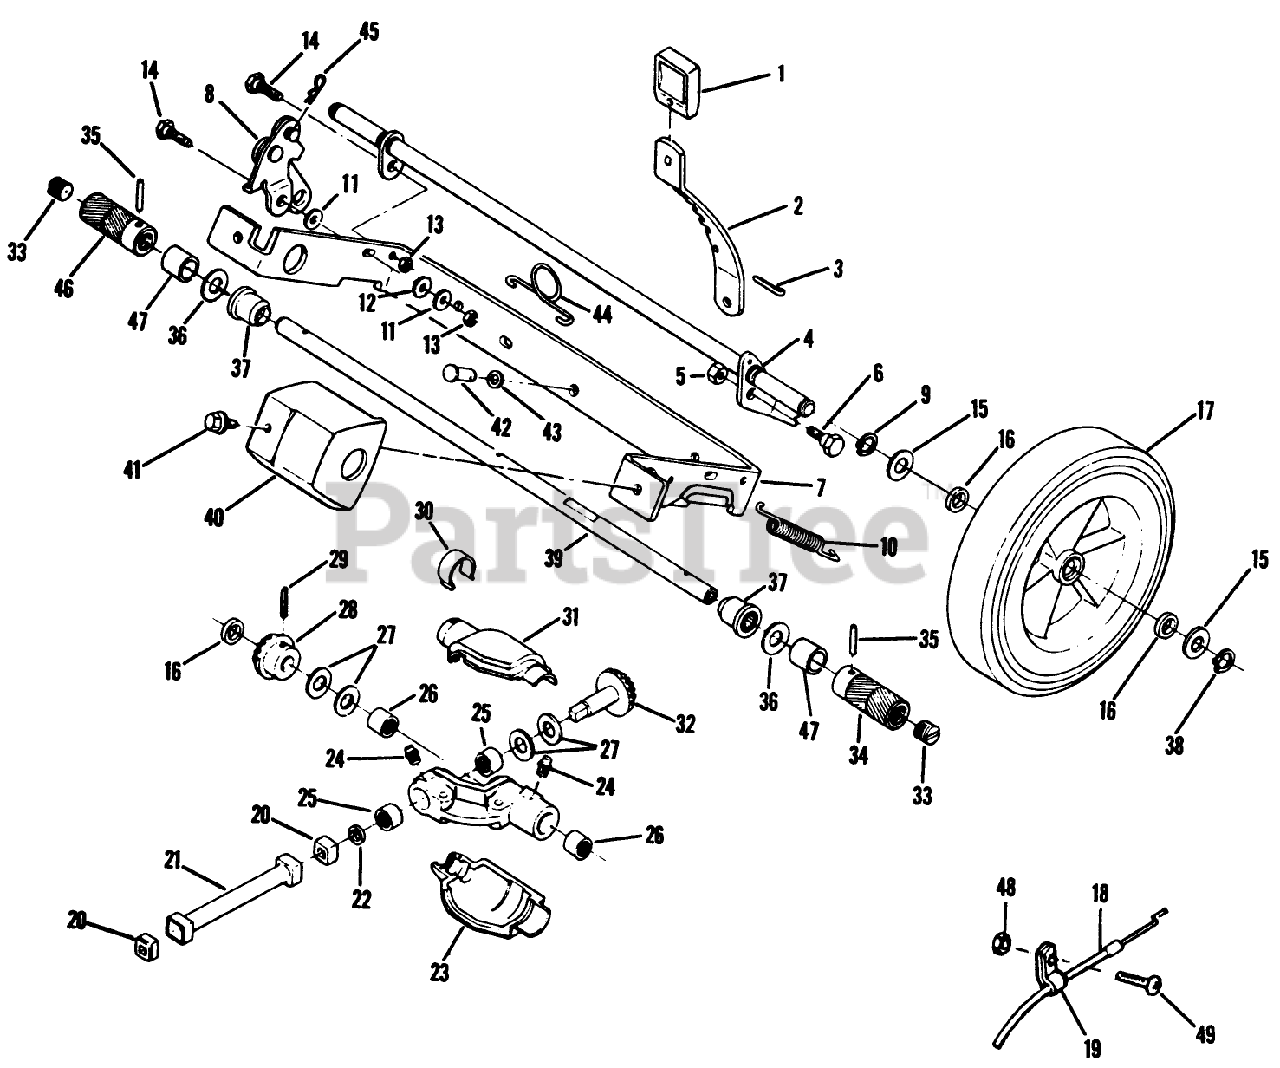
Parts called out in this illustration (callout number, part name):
4	AXLE & TORQUE LUG ASM
5	LOCKNUT E
6	BOLT RB&W
7	BRK-21" AXLE
9	RET RING
11	WASHER S
13	STOP NUT
14	BOLT RB&W
20	BUSHING
24	**FITTING LINCOLN
27	THRUST WASHER
28	GEAR ADVANCE
29	ROLL PIN
31	GEAR COVER UPPER
32	GEAR BEST
33	GREASE PLUG
34	ROLLER-LEFT
36	THRUST WASHER
37	SLEEVE &BEARING AY
38	RET RING
39	DRIVE SHAFT & TAG
43	WASHER SPRING LAR
44	SPRING N.A.S
